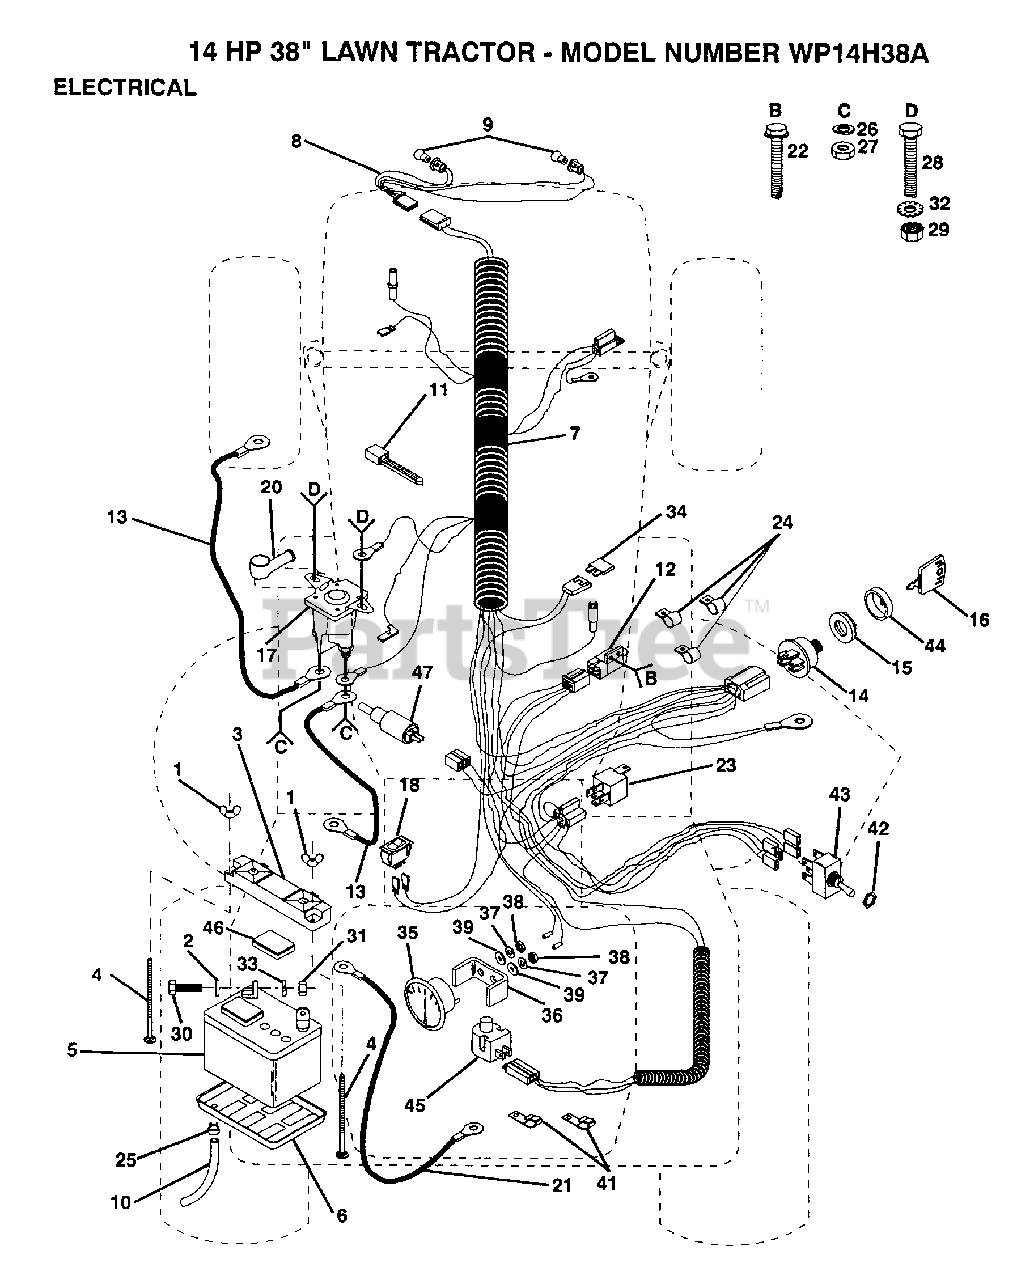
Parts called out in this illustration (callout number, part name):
2	WASHER
4	BOLT
6	"TRAY T, BATTERY"
7	"HARNESS,IGN."
11	WIRE TIE
12	SWITCH INTERLOCKT
13	CABLE-BATTERY T
15	NUT IGNITION
16	KEY
18	SWITCH LT
21	CABLE T
22	SCREW
23	RELAY ASSY T
24	CLIP T
25	HOSE CLAMP T
27	NUT
28	BOLT
29	NUT
30	BOLT LT
33	LOCKWASHER
34	FUSE HYT
35	AMMETER T
39	WASHER
41	CLIPT
42	HEX NUT T
45	SWITCH SEAT
46	"CAP,BATTERY "
47	DIODE ASM.
